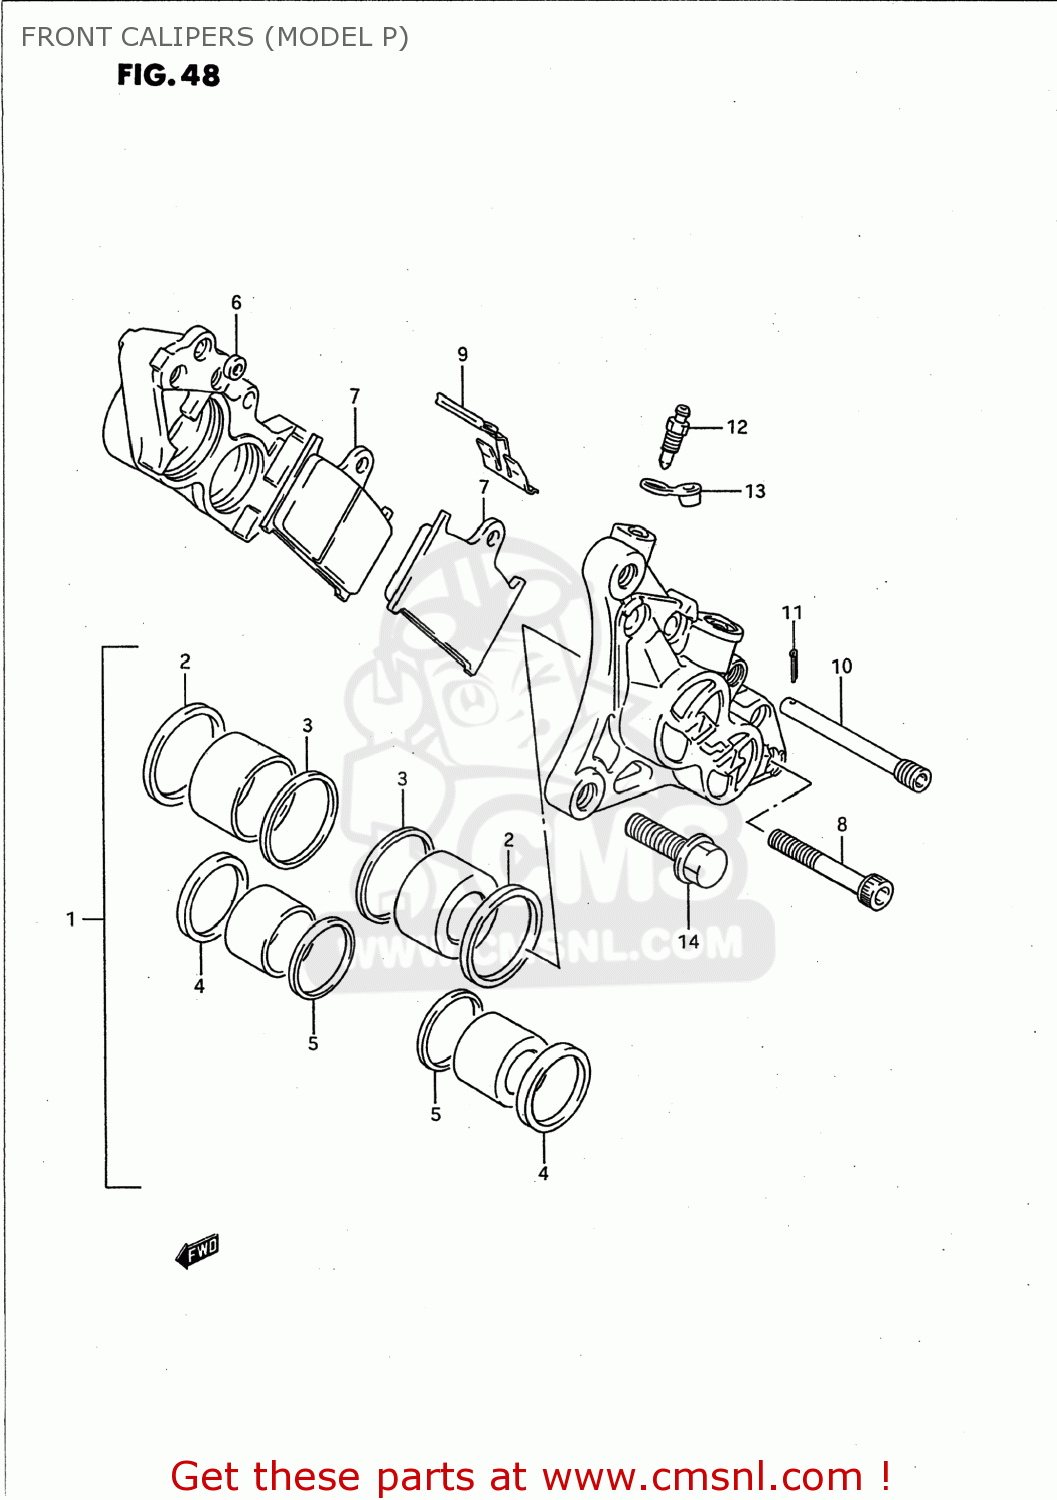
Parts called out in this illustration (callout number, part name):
1	PISTON SET
2	SEAL,PISTON
3	BOOT,PISTON
4	SEAL,PISTON
5	SEAL
6	SEAL
7	PAD,BRAKE
8	BOLT
9	SPRING
10	PIN,HANGER
11	COTTER PIN
12	BLEEDER
13	CAP,BLEEDER
14	BOLT
